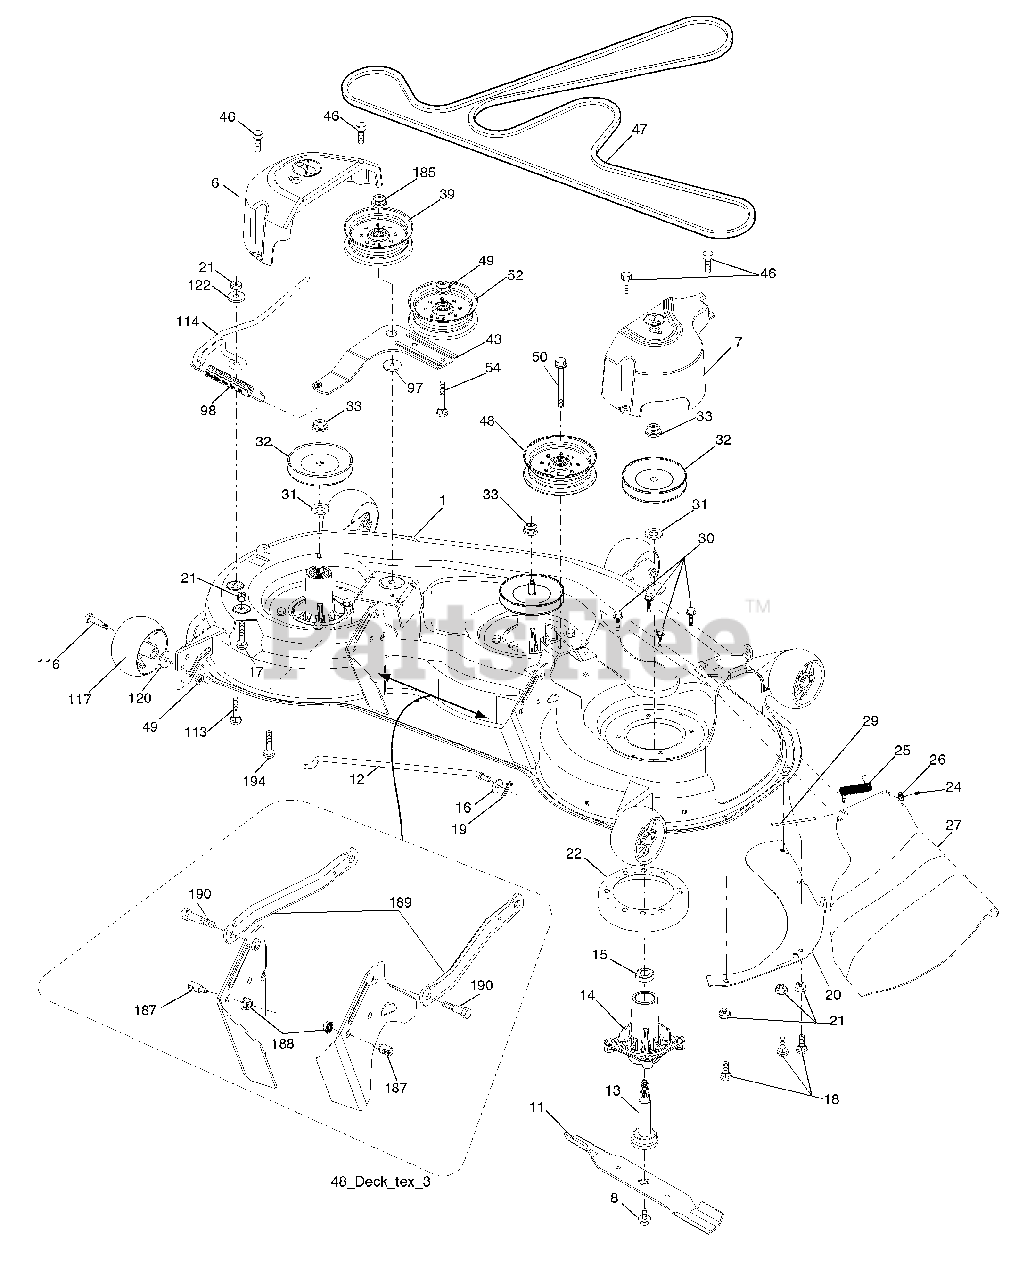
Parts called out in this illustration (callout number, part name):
1	Deck Weldment Mower
6	Cover Mandrel LH
7	Cover Mandrel RH
8	Bolt 7/16 Asm. Blade
11	Blade High Lift
12	Rod Anti Sway
12	Blade Mulching
13	Shaft Asm. w/Lower Bearing
14	Housing, Mandrel
15	Bearing, Ball, Mandrel
16	Washer 3/8
18	Bolt RdHd 5/16-18 unc x 5/8
19	Pin Cotter 5/16 Bowtie
20	Baffl e Vortex
21	Nut, Crownlock 5/16-18 unc
22	Stripper Mandrel
24	Cap Sleeve
25	Spring, Torsion
27	Defl ector Shield
29	Rod, Hinge
30	Screw, Thdroll Washer Head
31	Washer, Spacer Mower Vented
32	Pulley, Mandrel
33	Nut, Flg. Top Lock
39	Pulley, Idler, Stationary LH
43	Arm, Idler
46	Screw, Thdroll. 1/4-20 x 5/8
47	Belt Deck Drive
48	Pulley Idler
49	Nut, Lock Flg. 3/8-16 unc
50	Bolt Carr SH 3/8-16 x 1-1/2 Gr.5
52	Pulley Idler Clutching
54	Screw 3/8-16 x 2-1/4
97	Washer Hardened
98	Spring Drive
113	Bolt Rdhd Sqnk 5/16-18 x 3/4
114	Rod Tension Relief
116	Bolt, Shoulder
117	Gauge Wheel
120	Washer 13/32 x 1-1/4 x 12 Ga.
122	Bushing Tension Relief
185	Nut Lock Flange 7/16-14 Gr. 5
187	Stud Fastener w/"D" Anti-Rotation
188	Nut Lock Hex Flange 5/16-18
189	Arm Susp. Mower Rear
190	Bolt Shoulder
194	Bolt Carr Sqnk 7/16-24 x 2
194	Mandrel Asm. Service
194	Replacement Mower, Complete
